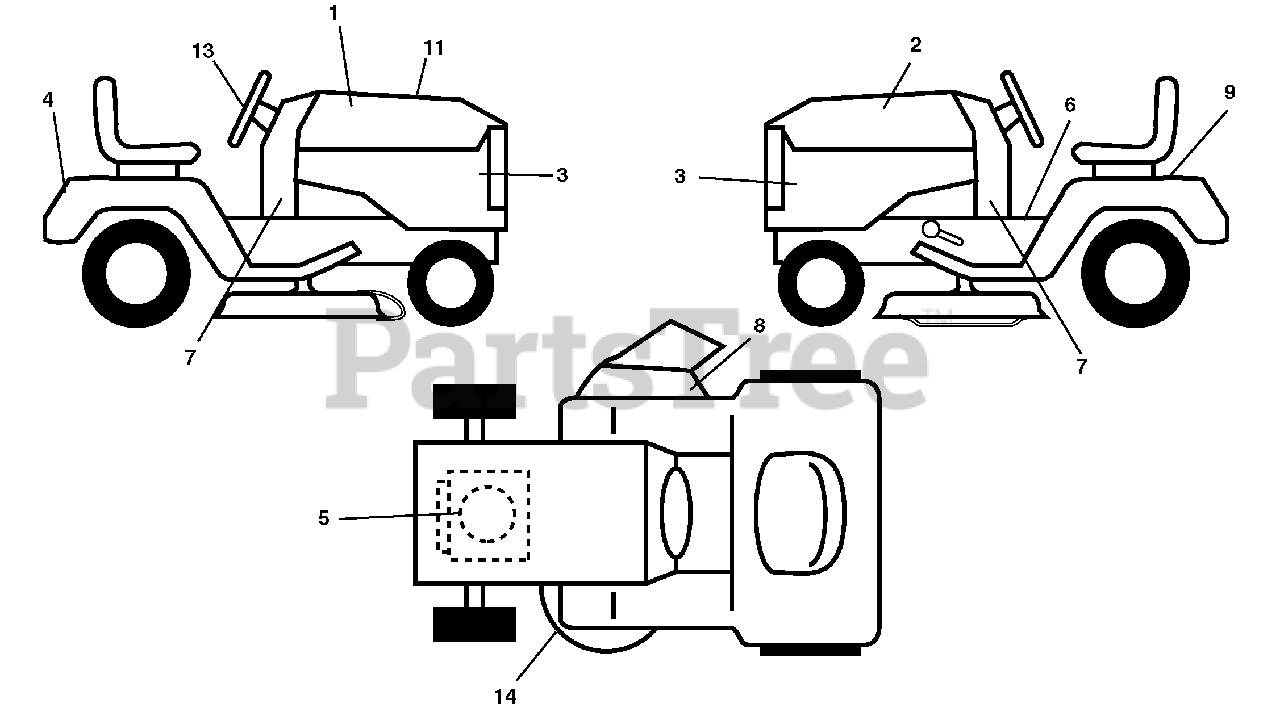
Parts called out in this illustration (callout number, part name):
1	Decal, Hood RH
2	Decal, Hood LH
3	Decal, Side Panel
4	Decal, Fender
5	Decal, Engine
6	Decal, Fender Operator's
7	Decal, Lower Dash
8	Decal, Warning
9	Decal, Battery Dnge/Poi
11	Decal, Replacement
13	Decal, Steering Wheel
14	Decal, Mower Schematic
14	Pad, Footrest, RH
14	Decal, Bypass
14	Pad, Footrest, LH
14	Manual, Operator's E/Fr
14	Manual, Parts
